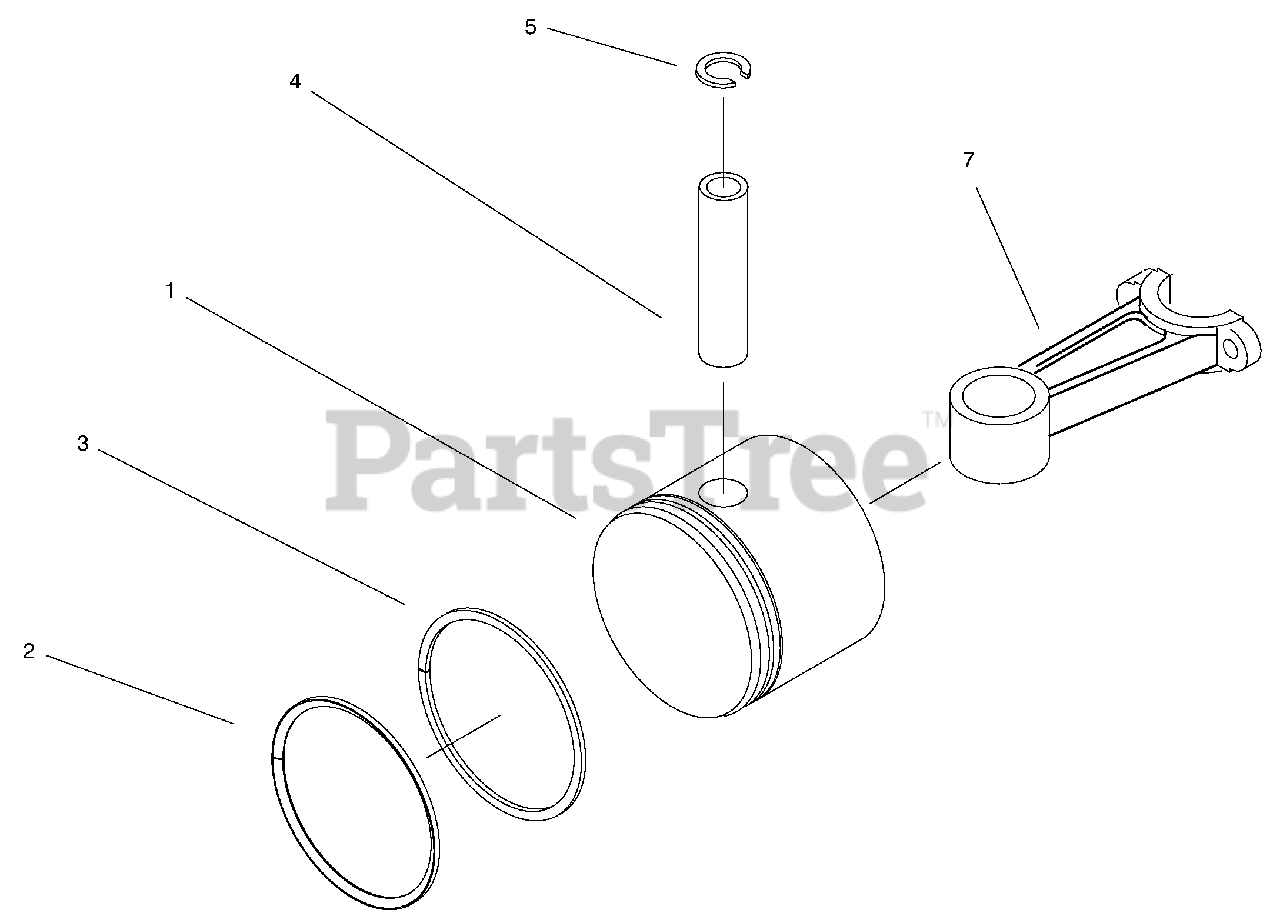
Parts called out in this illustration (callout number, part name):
2	Ring-Piston
3	Ring-Piston
4	Pin-Wrist
5	Ring-Retaining
7	Connecting Rod ASM
